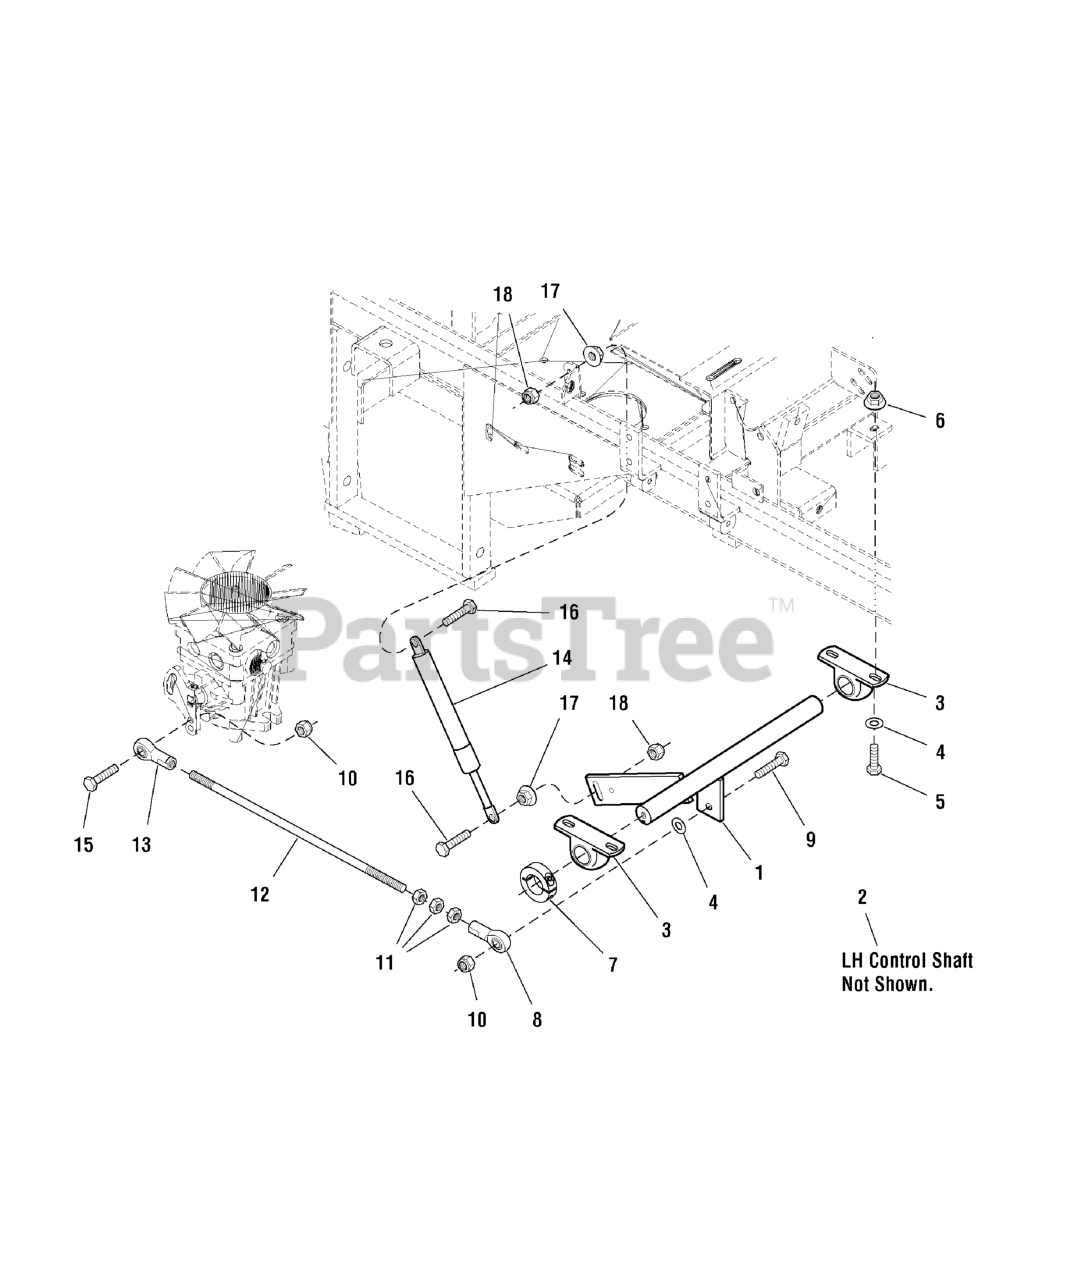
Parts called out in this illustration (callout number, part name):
1	CONTROL SHAFT-RH
3	BEARING, Pillow Block
4	WASHER, 5/16" SAE
5	BOLT, 5/16-18 X 1 GD5 YZ
6	NUT, 5/16-18 HEX SERRATED FLANGE (SMALL)
7	COLLAR, 1" Split
8	BALL JOINT 5/16-24 RH FEMALE BRONZE RACE
9	BOLT, 5/16-18 x 1-1/4
10	NUT, 5/16-18 Hex Nylon Lock
11	NUT, 5/16-24 Hex
12	HYDRO LINKAGE ROD
13	BALL JOINT 5/16-24 LH FEMALE BRONZE RACE
14	DAMPENER
15	BOLT, 5/16-18 x 1-1/8
16	BOLT, M8 x 35MM
17	NUT, M8-1.25 Hex Serrated Flange
18	NUT, M8-1.25 Hex Nylon Lock
